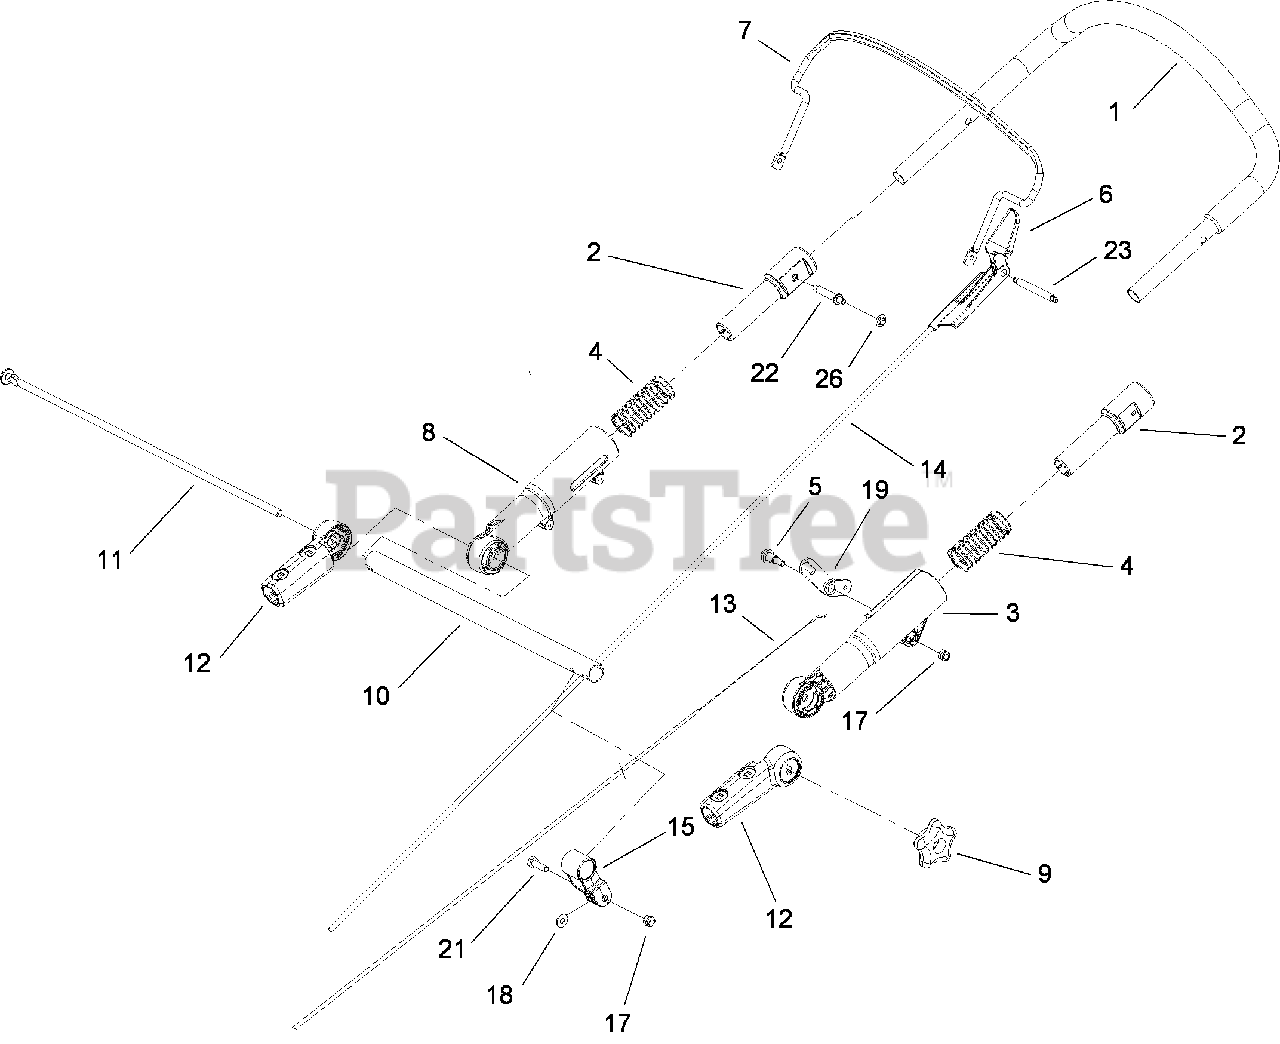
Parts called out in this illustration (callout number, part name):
1	UPPER HANDLE ASM
2	SLEEVE-INNER
3	SLEEVE-OUTER, LH
4	SPRING-COMPRESSION
5	BOLT-SHOULDER
6	STOP-PIVOT
8	SLEEVE-OUTER, RH
11	ROD-THREADED
12	MOUNT-HANDLE, LOWER
13	CABLE-TRACTION
14	CABLE-BRAKE
15	CLAMP-CABLE
17	NUT-LOCK, NI
18	WASHER-FLAT
19	LEVER-TRACTION
21	SCREW-HH
22	PIN-HANDLE
23	PIN-BAIL, LH
26	RETAINER-PUSH ON
